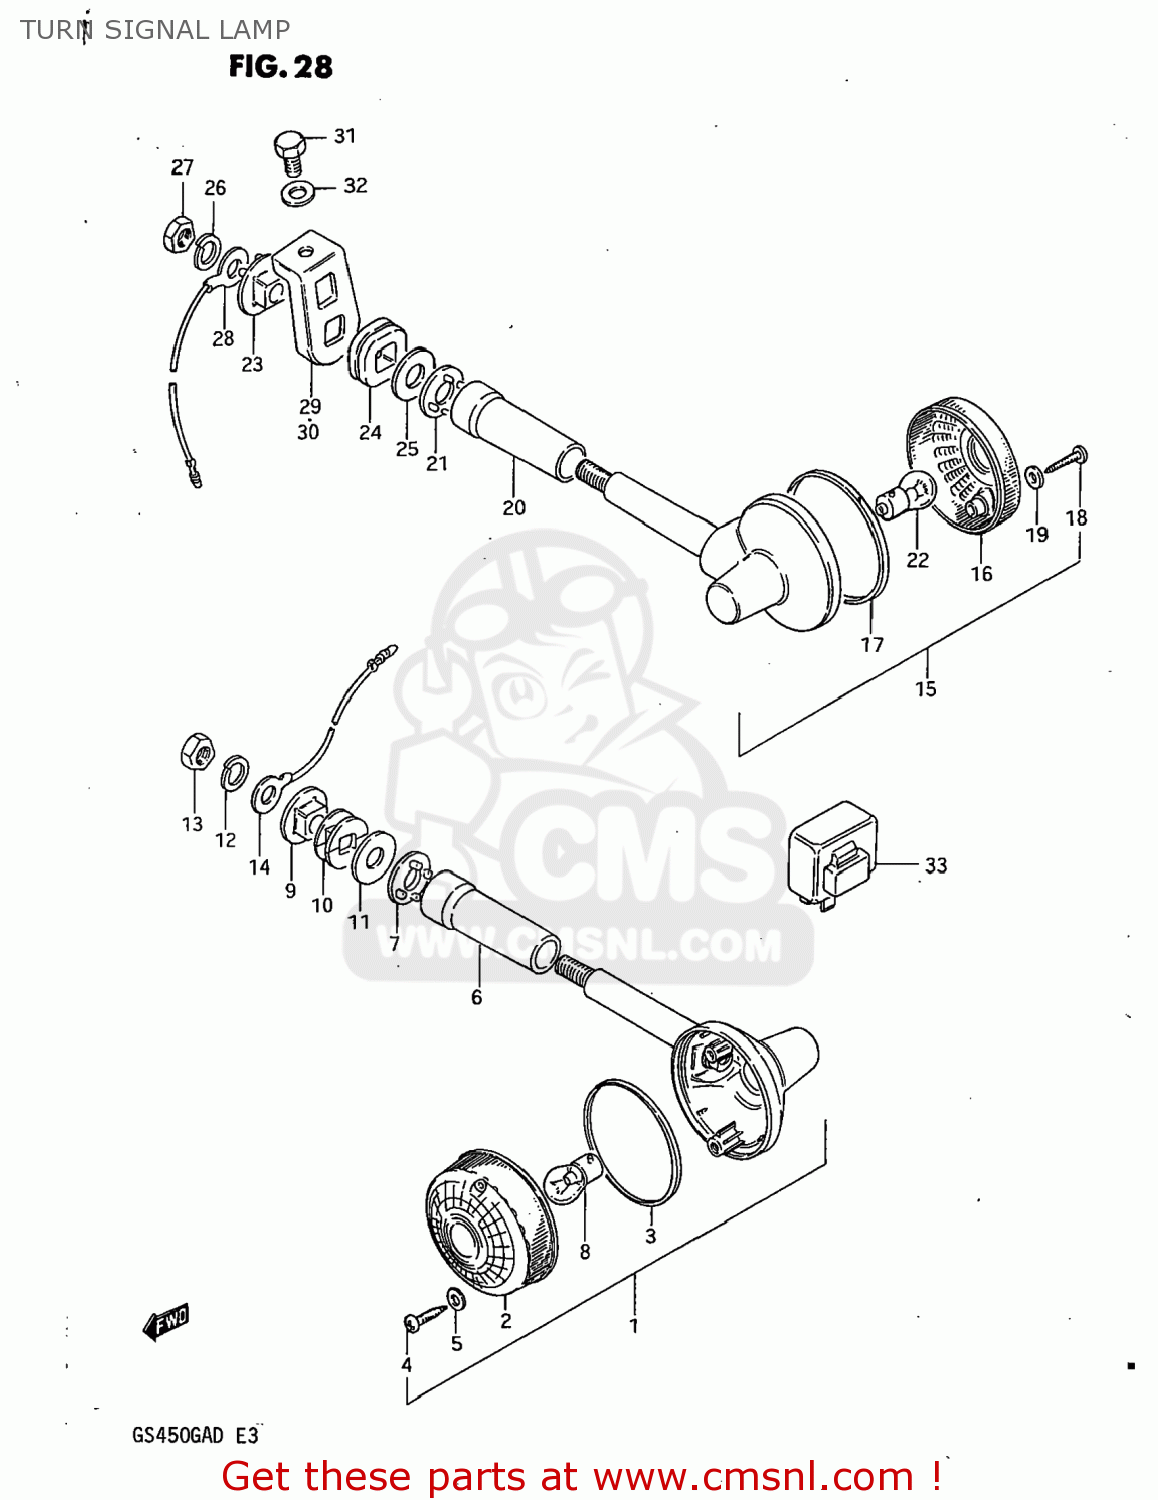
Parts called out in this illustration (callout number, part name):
1	LAMP ASSY,TURNSIGNAL
2	LENS
3	GASKET (NAS)
4	SCREW
5	GASKET (NAS)
6	COVER,STAY
7	SPACER
8	BULB(12V23W,STANLEY,A4577A)
9	SPACER
10	CUSHION
11	WASHER (10.5X30X2.3)
12	LOCK WASHER
13	NUT
14	LEAD WIRE,EARTH
15	LAMP ASSY,TURNSIGNAL
16	LENS
17	GASKET (NAS)
18	SCREW
19	GASKET (NAS)
20	COVER,STAY
21	SPACER
22	BULB(12V23W,STANLEY,A4577A)
23	SPACER
24	CUSHION
25	WASHER (10.5X30X2.3)
26	LOCK WASHER
27	NUT
28	LEAD WIRE,EARTH
29	BRACKET,REAR TURN SIGNAL
30	BRACKET,REAR TURN SIGNAL
31	BOLT 8X12
32	WASHER
33	RELAY,TURN SIGNAL
